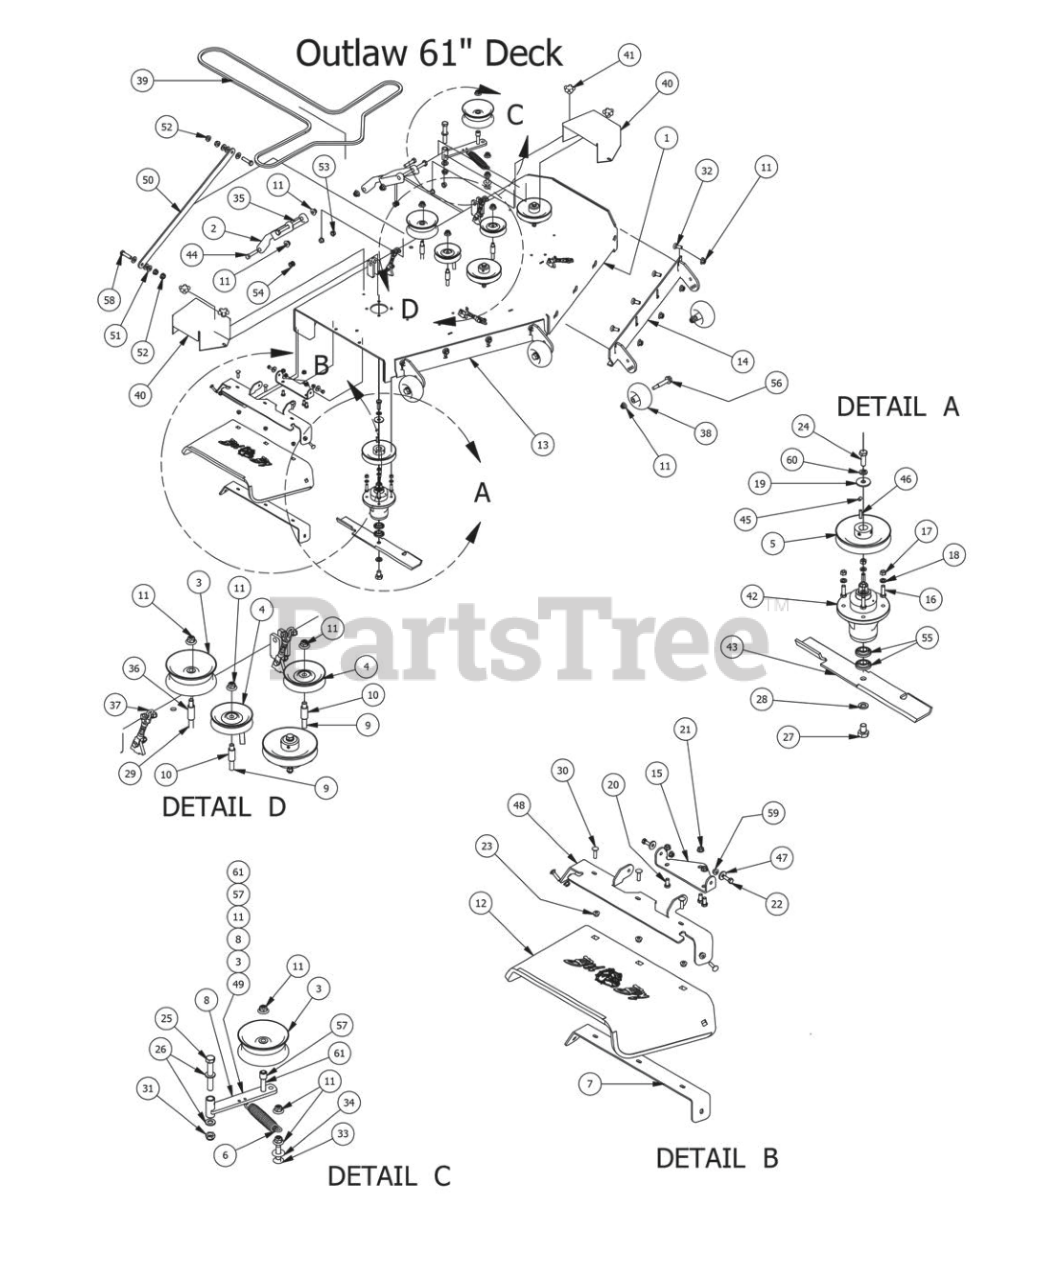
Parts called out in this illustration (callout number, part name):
1	61" Outlaw (Deck Only)
2	Deck Arm Assembly
3	5 3/4" Deck Idler Pulley
4	4 3/4" Idler Pulley
5	6 1/4" Drive Pulley
6	2009 Deck/Pump Idler Spring
7	60" Discharge Lower Bracket
8	Deck Idler Bracket
9	1/2 x 3 1/2 Flange Bolt Grade 8
10	Pulley Spacer
11	1/2-13 Nylon Insert Flange Nut
12	Rubber Discharge Chute
13	61 Outlaw Adjustable Deck Front (Left)
14	61 Outlaw Adjustable Deck Front (Right)
15	Discharge Chute Hanger (deck mounted)
16	3/8" x 1 1/4" Hex Bolt
17	3/8-16 Hex Nuts Zinc
18	3/8 Lockwasher Zinc
19	1/2 Belleville Washer
20	3/8" x 3/4" Hex Bolt
21	3/8" Flange Nut
22	5/16" x 1" Bolt
23	5/16" Flange Nut Zinc W/Serrations
24	1/2"-20 x 1 1/2 - Grade 5 Fine Thread Bolt
25	5/8" x 4" Hex Bolt
26	.635 ID Plastic Washer
27	5/8" x 1 1/2" Grade 8 Bolt
28	5/8" Lock Washer
29	1/2" x 4" Bolt (Grade 8)
30	5/16" x 1 1/4" Carriage Bolt
31	5/8-11 Nylon Insert Jam Half Nut
32	1/2" x 1 1/4 Carriage Bolt
33	1/2 x 2" Carriage Bolt
34	1/2" Flat Washer
35	1/2" x 5 1/2" Bolt
36	1 3/4" Pulley Spacer
37	2-Link Adjustable Deck Hange
38	Deck Wheel
39	B178 Belt For 61 Inch Outlaw
40	Pulley Cover
41	5/16" Knob
42	Double Bearing Spindle
43	61 inch Fusion Blade
44	1/2-13X 2-1/4 GR Hex Bolts
45	5/16 Set Screw
46	1/4" x 1" Key
47	.360 ID Plastic Washer
48	60" Discharge Chute Upper Hanger
49	Deck Idler Assembly-parts of Assembly 3,8,11,57,61
50	Panhard Linkage Bar
51	.505 Nylon Spacer
52	1/2" Flange Nut
53	Flange Bushing For Deck Arm upper
54	Flange for Lower Deck Arm
55	Double Bearing For Spindle
56	Deck Wheel Bolt-2011 Outlaw
57	3/4 OD x 1/2 ID x 3\4 Length
58	1/2-13x2 Grade 8 Hex Bolt
59	5/16" Nylon Flange Nut
60	1/2" Lock Washer
61	1/2-13 x GR 5 Hex Bolt Zinc
